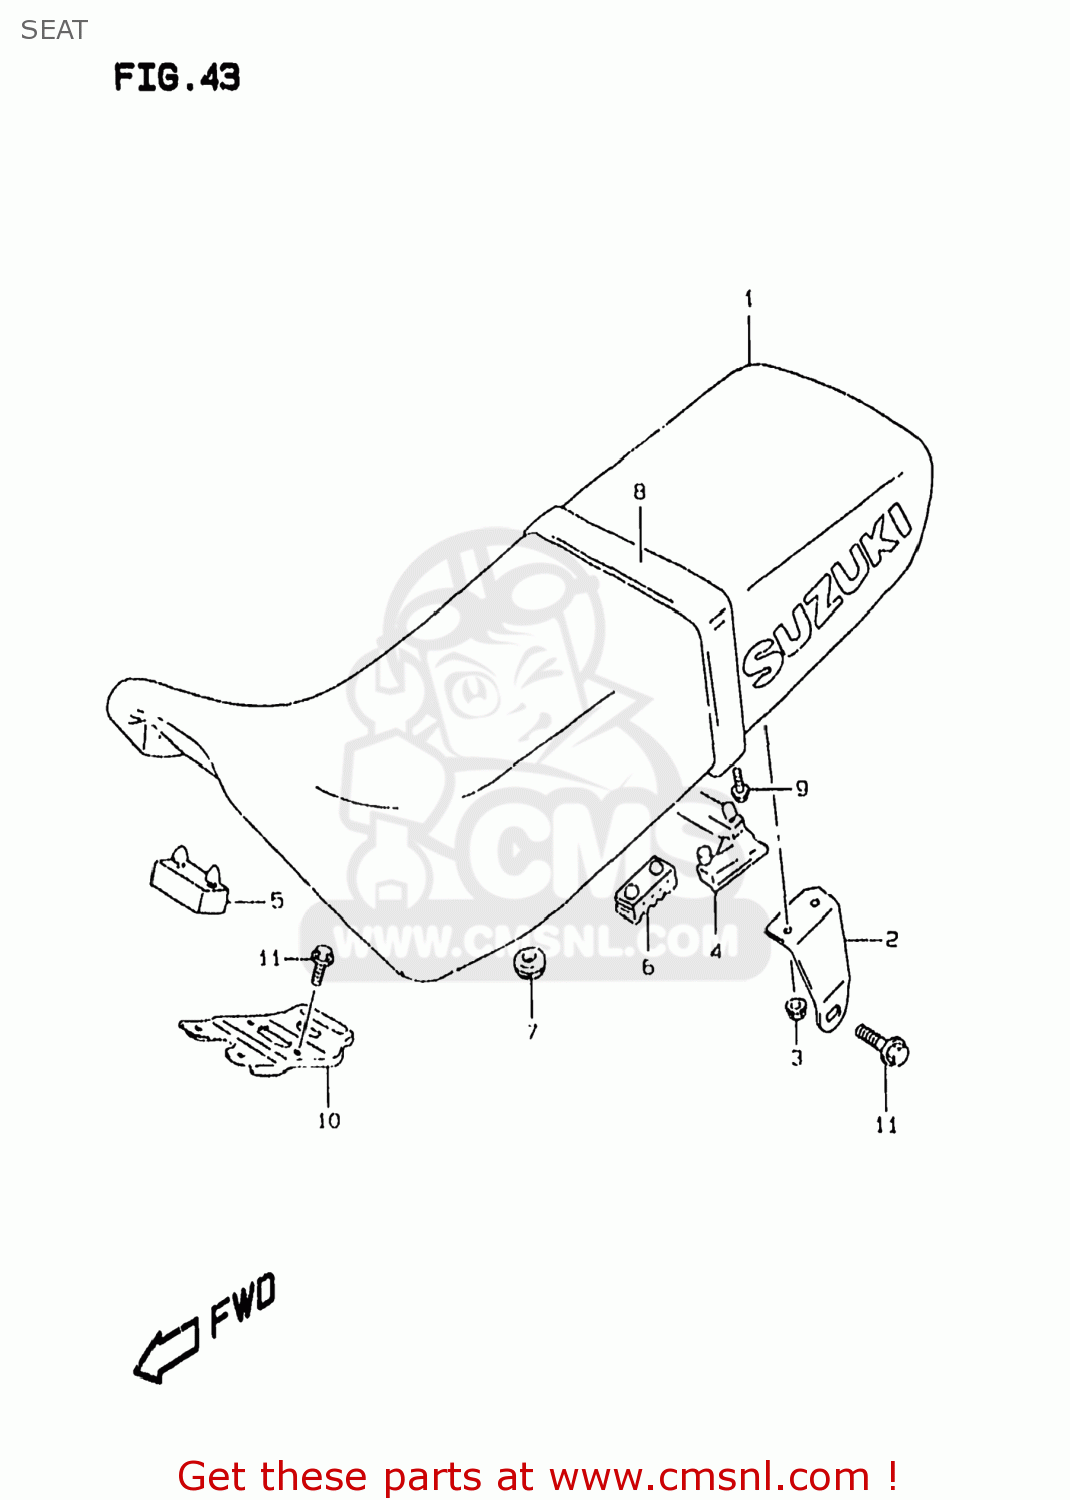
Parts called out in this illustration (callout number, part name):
1	SEAT SET
2	BRACKET,SEAT,R
3	NUT
4	CUSHION
5	CUSHION
6	CUSHION,SEAT(40X20X15)
7	CUSHION
8	BAND ASSY,SEAT
9	BOLT
10	PLATE,SEAT FR HOOK
11	BOLT
